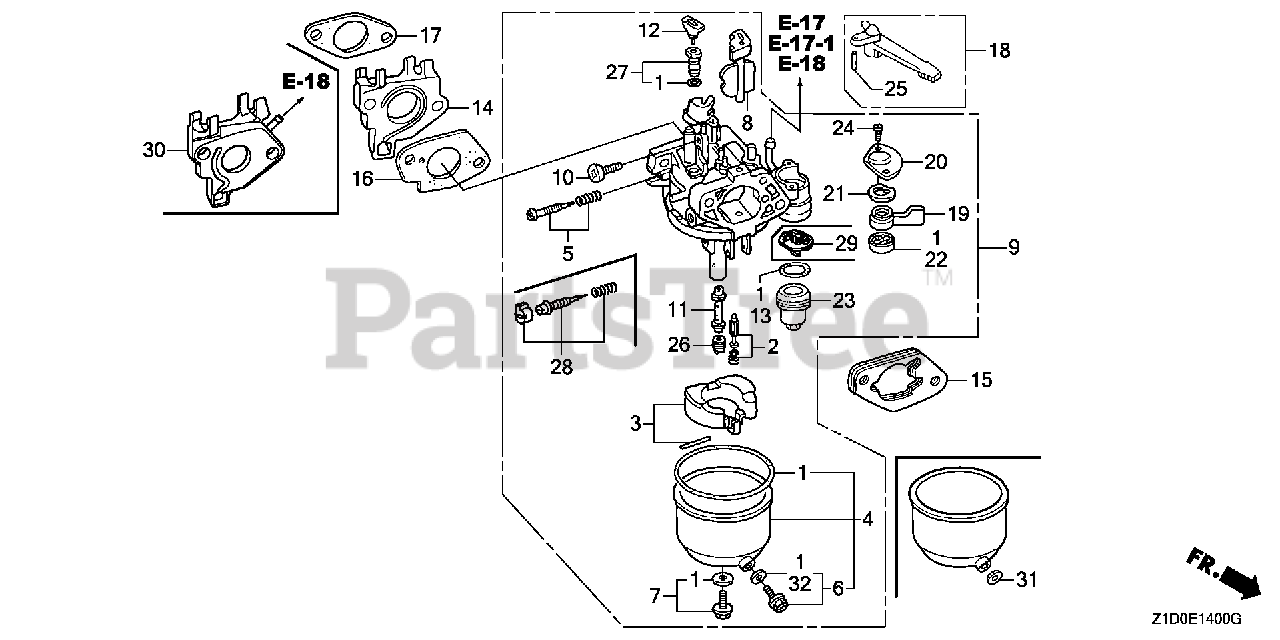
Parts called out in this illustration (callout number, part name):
1	GASKET SET (INCLUDES 16173-001-004)
2	VALVE SET, FLOAT
4	CHAMBER SET, FLOAT
6	SCREW SET, DRAIN
9	CARBURETOR ASSY. (BE21N A)
10	SCREW, THROTTLE STOP
11	NOZZLE, MAIN
12	COLLAR, SETTING
13	GASKET, FUEL STRAINER CUP
14	INSULATOR, CARBURETOR
15	SPACER, CARBURETOR
16	GASKET, CARBURETOR
17	GASKET, INSULATOR
18	LEVER, CHOKE (STD)
19	LEVER, PETCOCK
20	PLATE, LEVER SETTING
21	SPRING, PETCOCK LEVER
22	GASKET, PETCOCK
23	CUP, FUEL STRAINER
24	SCREW, PAN (3X6)
25	PIN, SPRING (2X12)
26	JET, MAIN (#85)
26	JET, MAIN (#88)
26	JET, MAIN (#90)
27	JET SET, PILOT (#40)
28	SCREW SET, PILOT
29	FILTER, CUP
31	WASHER, PLAIN (6.2X10.7 DRAIN)
